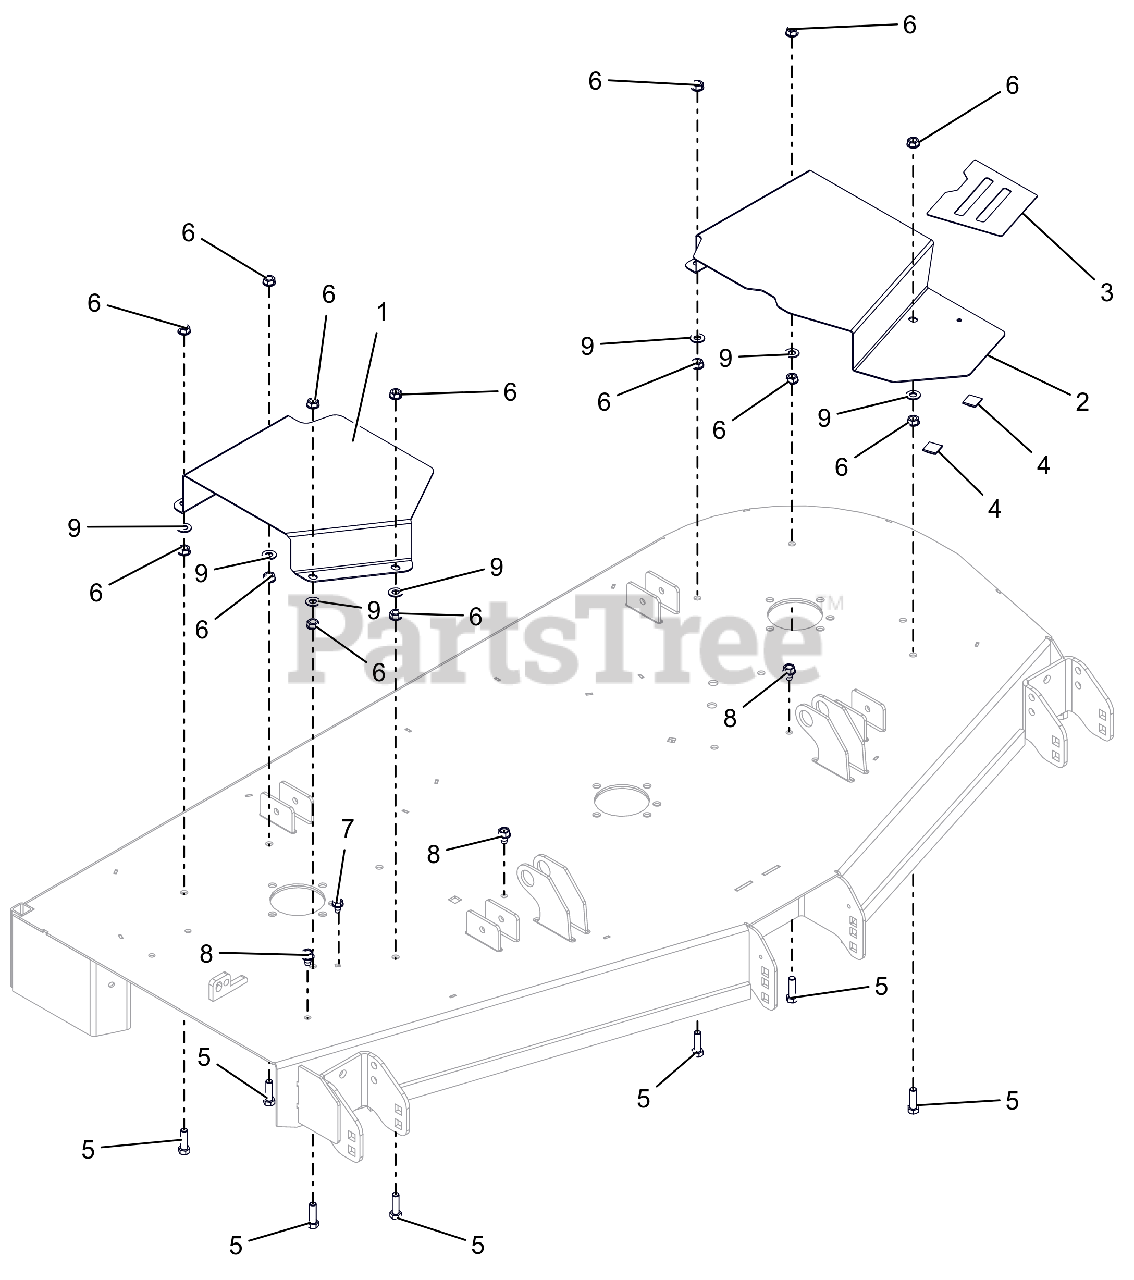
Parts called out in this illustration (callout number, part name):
1	COVER, BELT 52" & 60" RIGHT
2	COVER, BELT 60" LEFT
3	GRIP, TAPE 52-60 BELT COVER
5	BLT, HEX .38-16X1.25 G5 ZCC
6	NUT, SPNLK-FLG .38-16 G5 ZCC
7	SCR,TAP .312-18X.50 HWH TR ZCC
8	SCR,TAP .375-16X.50 HWH TR ZCC
9	WSHR,FLT .406X.812X.065 ZCC
